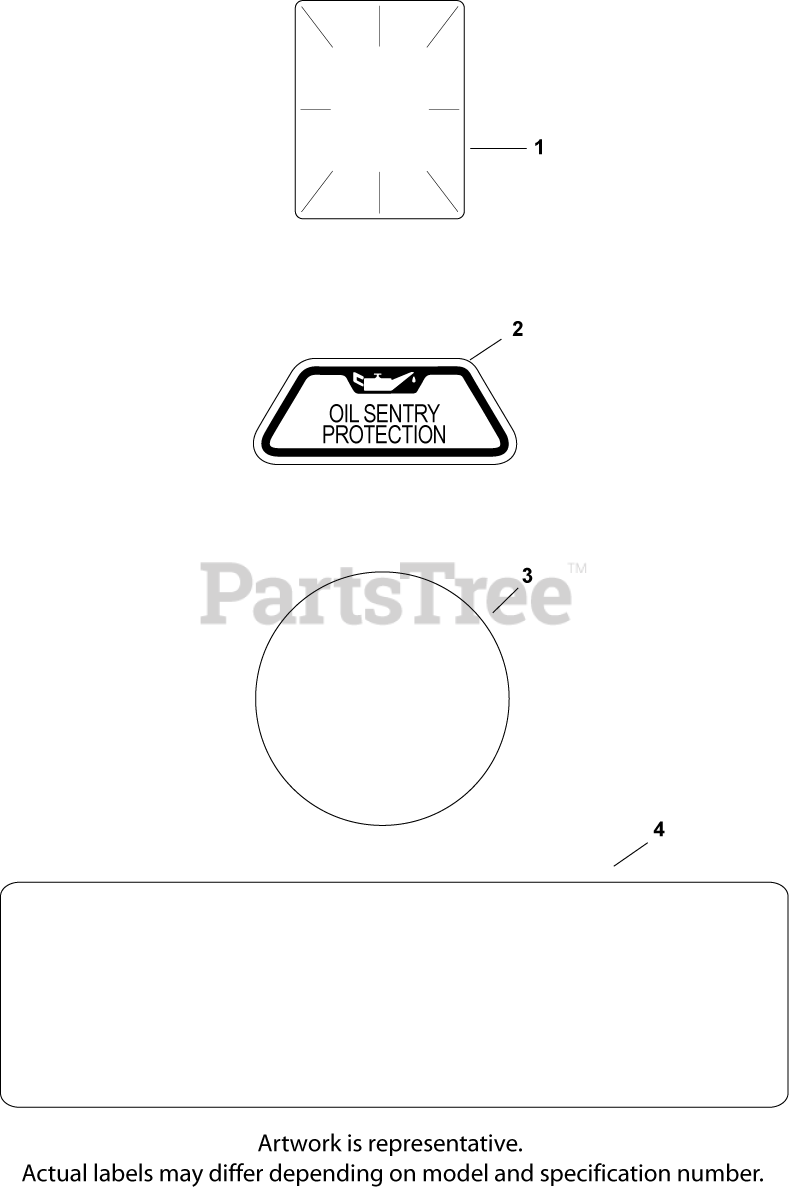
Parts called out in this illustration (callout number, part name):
1	DECAL, CLEAR LAMINATE USE 25 113 70-S
2	DECAL, OIL SENTRY - (#DSC)
3	DECAL, GRASS SCREEN USE 24 113 499-S
4	DECAL, 22 HP
